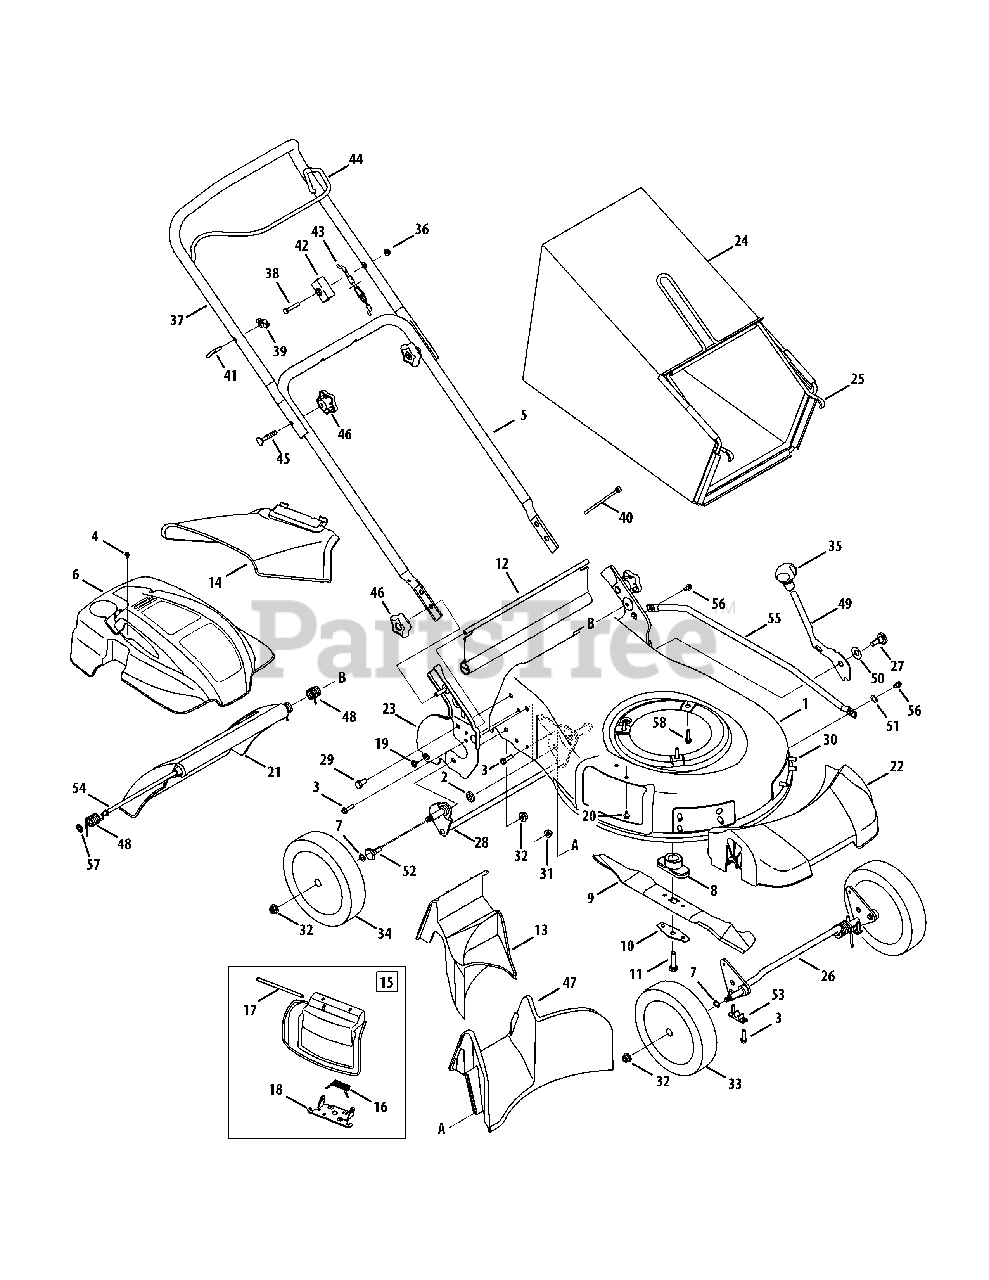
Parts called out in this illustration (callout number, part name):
2	Spacer, .515 x 1.00 x .310 Lg.
3	Screw, 1/4-15 x 1.000
4	Screw, HL, #12-16 x 1.00
5	Lower Handle
6	Engine Shroud
7	Washer, Wave, .510 x .750 x .017
8	Blade Adapter
9	Mulching Blade
10	Blade Bell Support
11	Screw, 3/8-24 x 1.50
12	Trailing Shield
13	Rear Mulch Plug
14	Side Discharge Chute
15	Mulch Plug (Incl. 16-18)
16	Torsion Spring
18	Chute Deflector Adapter
19	Screw, #10-16 x .500
22	Front Cover
23	Handle Bracket - RH
23	Handle Bracket - LH
25	Grass Bag Frame
26	Front Bracket Assembly
27	Screw, Shoulder, .50 x .66
28	Rear Bracket Assembly
29	Hhcs, 5/16-18 x .625
30	Screw, 5/16-14 x .750
31	Nut, Flange Lock, 5/16-18
32	Nut, Flange Lock, 3/8-16
33	Front Wheel
34	Rear Wheel
36	Nut, Flange Lock, 1/4-20
37	Upper Handle
38	Screw, 1/4-20 x 1.50
40	Cable Tie
41	Rope Guide
42	Control Cable Mount
43	Control Cable
44	Blade Control
45	Bolt Carriage, 5/16-18 x 2.0
47	Rear Baffle
48	Door Torsion Spring - RH
48	Door Torsion Spring - LH
49	Spring Lever
50	Washer, Bell, .510 x 1.14 x .040
51	Washer, Wave, .385 x .598
52	Screw, Shoulder, .500 Dia. X .434
53	Bushing, Lock, .505 Dia. X .62
54	Rear Door Pivot Rod
55	Cross Bracket
56	Screw, 1/4-20 x .50
57	Nut, Spd.
58	Screw, tt, 3/8-16 x 1.00
